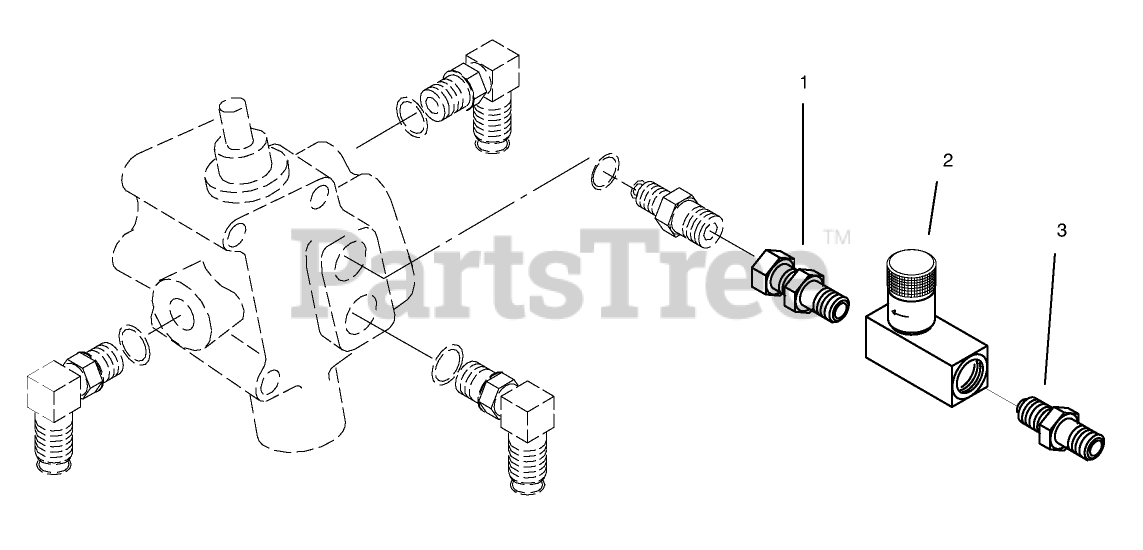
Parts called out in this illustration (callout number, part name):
1	FITTING-SWIVEL STRAIGHT
2	VALVE-ADJUSTABLE FLOW
3	FITTING-MALE
